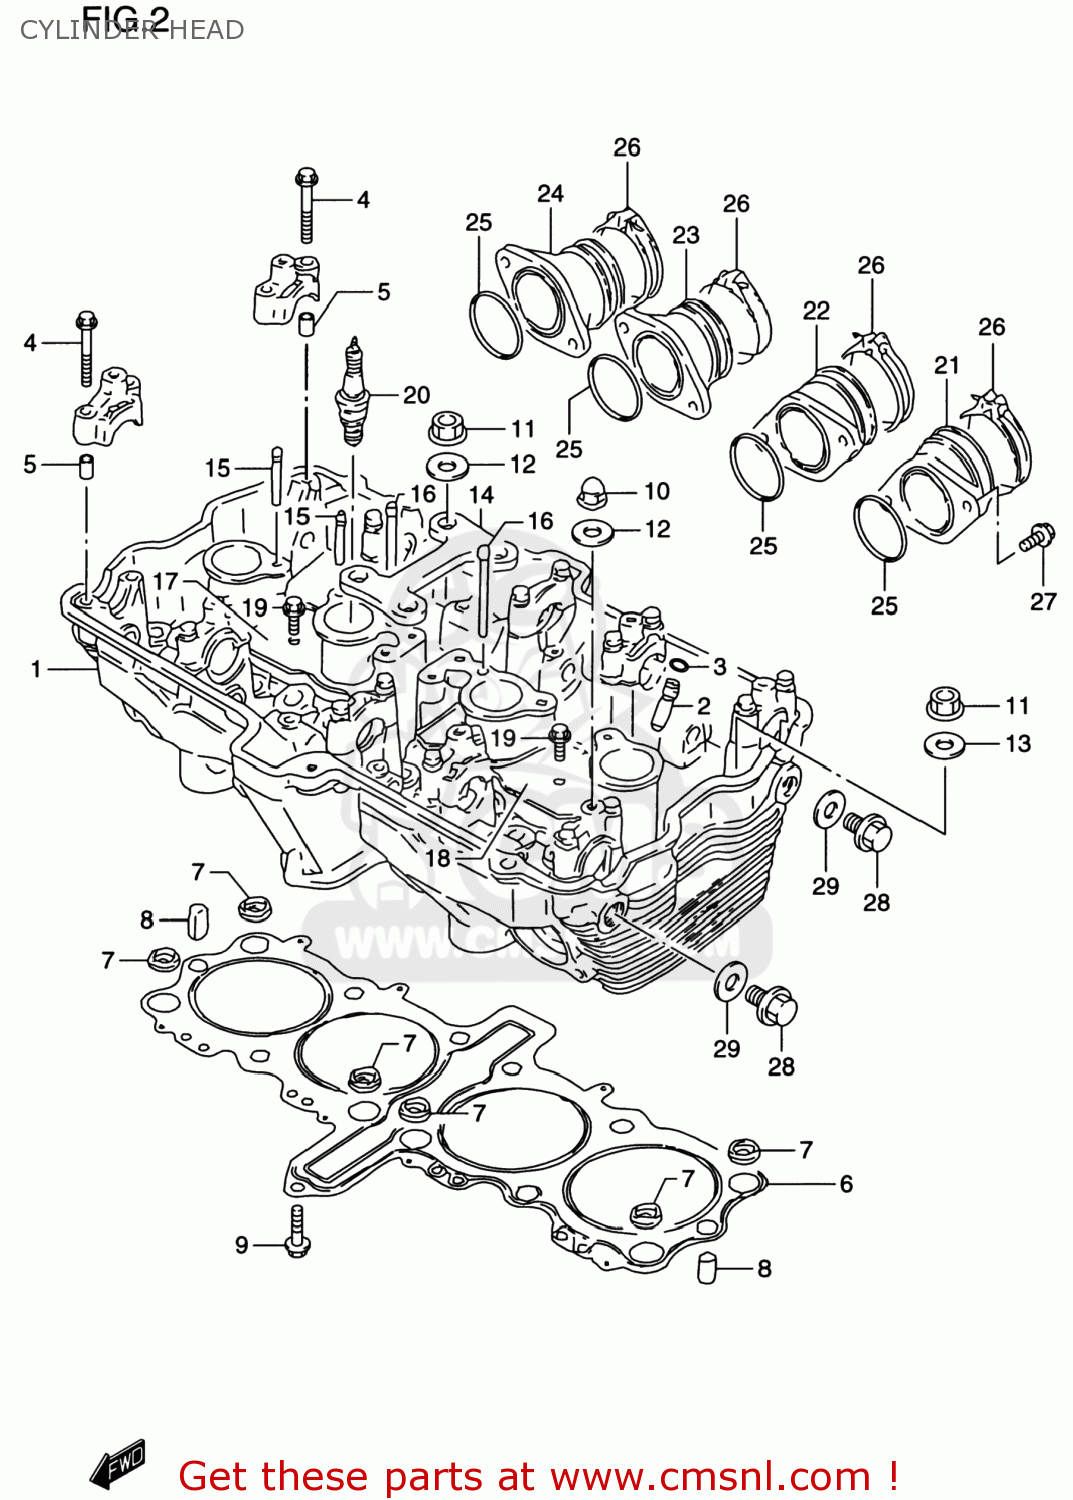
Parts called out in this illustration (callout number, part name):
1	HEAD ASSY,CYLINDER
2	GUIDE,VALVE
3	RING,SNAP
4	BOLT(6X39)
5	PIN(6.2X8X11)
6	GASKET,CYLINDER HEAD
7	O-RING,HEAD GASKET
8	PIN
9	BOLT
10	NUT
11	NUT
12	GASKET(10.2X20X2).3 (NAS)
13	WASHER (10.5X22X2.3)
14	PLATE,HEAD REINFORCEMENT
15	PIPE,OIL NO.1
16	PIPE,OIL NO.3
17	PLATE,OIL PIPE,R
18	PLATE,OIL PIPE,L
19	BOLT
20	PLUG,SPARK(JR9B)
21	PIPE,INTAKE NO.1
22	PIPE,INTAKE NO.2
23	PIPE,INTAKE NO.3
24	PIPE,INTAKE NO.4
25	O RING(D:2.4,ID:39.7)
26	CLAMP
27	BOLT MAGNETO S
28	PLUG
29	GASKET(13.8X18.8X4.8) (NAS)
